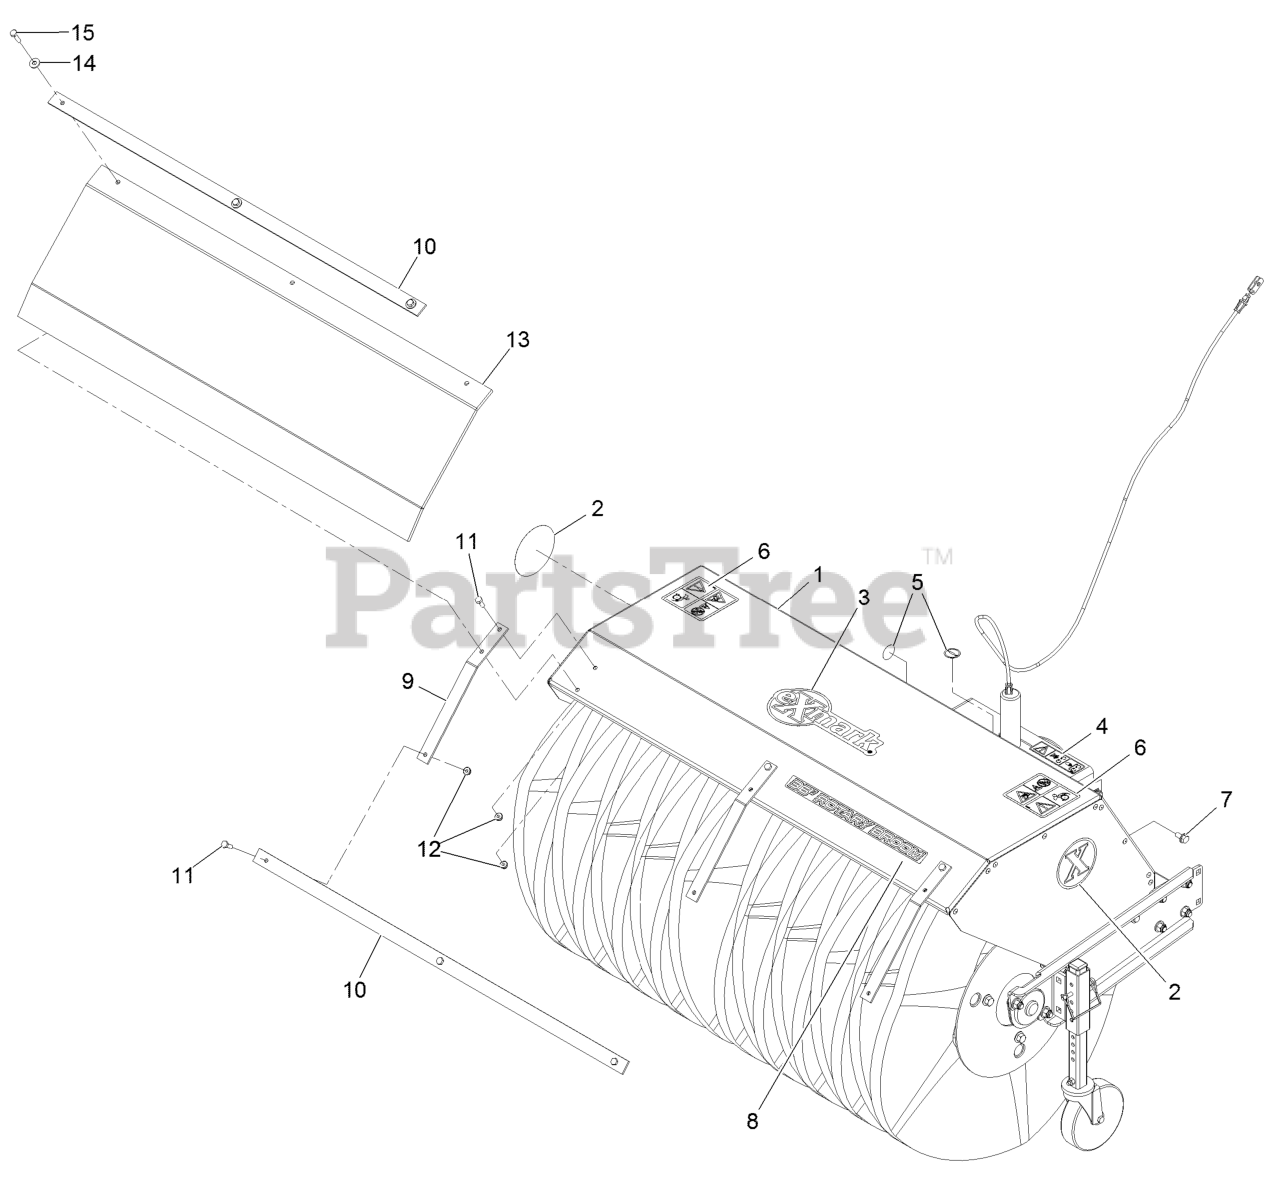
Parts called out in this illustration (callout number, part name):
1	Broom ASM
2	Decal-Exmark X-Logo 3.85
3	Decal, Exmark
4	Decal-Cover, Missing
5	Decal-Grease
6	Decal-Warning
7	Screw-HWHTF
8	Decal-36 Rotary Broom
9	Strap-Support, Deflector
10	Strap-Support, Broom Deflector
11	Screw-HH 1/4-20 X 3/4
12	Nut-Nyloc 1/4-20 Flg
13	Deflector-Broom
14	Washer-1/4 Std
15	Screw-HH 1/4-20 X 1
